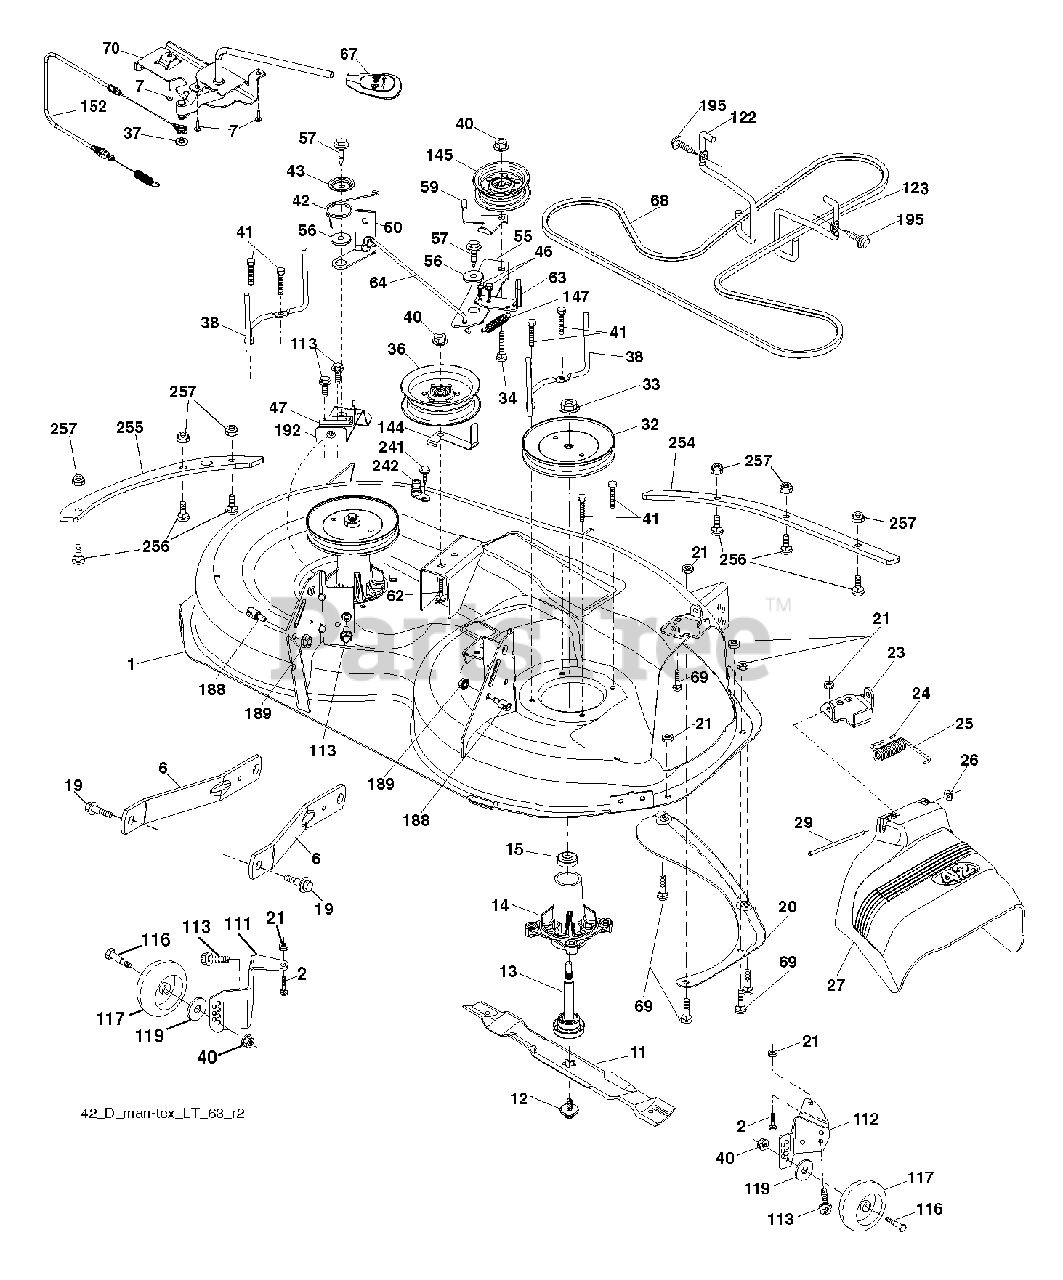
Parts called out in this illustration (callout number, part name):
1	DECK.SVC.42"2GW
2	BOLT 5/16C X 3/4" CARRIAGE
6	ARM.SUSPENSION.MOWER.R
7	SCREW.#10 X 0.750.BOS
11	42" HI-LIFT BLADE
12	SCREW.SEMS.7/16-20X1.HEX.HEAD
13	SHAFT ASM.MNDRL.N/GREASEABLE
14	HOUSING.MANDREL.4PT.
15	BEARING.MANDREL.TOP.EXTENDED
19	BOLT.SHOULDER
20	BAFFLE.VORTEX
21	LOCKNUT
23	BRKT.DEFLECTOR.38"2005+
24	CAP-SLEEVE LT
25	SPRING.TORSION.DEFLECT
26	NUT PUSH M
27	SHIELD.DEFLECTOR.MOWER.42"BLAC
29	ROD.HINGE
32	PULLEY.MANDREL.5.438.PD
33	NUT.FLANGE.LOCK.TOP
34	BOLT.3/8-16X1.50
36	PULLEY.IDLER.2006
37	WASHER
38	KEEPER.BELT.MANDREL.PULLEY
40	NUT LOCK FLG 3/8-16 UNC
41	BOLT.HEX.WASHR.HED.313-18X1.19
42	SPRING.TORSION.BRAKE
43	SRPING.TORSION.RETAINE
46	SCREW.1/4-20X5/8
47	BRKT.CLUTCH.CABLE
55	IDLER.ARM.42"
56	SPACER.RETAINER
57	SCREW 3/8-16X1
59	GUARD, BELT
60	ARM BRAKE MOWER
63	ARM BRAKE MOWER
64	LINKAGE.BRAKE.ASM.ZINC
67	HANDLE.CLUTCH.CABLE.LT
68	BELT.DECK.DRIVE.42"
69	BOLT
70	CLUTCH.ASM.MANUAL.YT.PREDATORQ
111	BRKT.WHEEL.GAUGE.LH.42"
112	BRKT.WHEEL.GAUGE.RH.42"
113	BOLT.5/16HEX.WHS.HD
116	BOLT M
117	Gage Wheel, Rally Narrow
119	WASHER
122	KEEPER BELT ENGINE LH
123	KEEPER BELT RH
144	KEEPER.BELT.MOWER
145	PULLEY.IDLER.48"PRIMARY
147	RETURN SPRING
152	CABLE.MECHANICAL.CLUTCH
188	STUD.FASTNER.W/ANTI-ROTATE
189	NUT LOCK HEX FLANGE 5/16-18
192	BRKT.BRAKE.STAND.LH.
195	SCREW, 3/8-16X3/4
241	SCREW.TT.#10-32X.5.3/8.FLANGE
242	PORT.WASHOUT
254	PLATES.RENFRC.42DECK.PT431FRNT
255	PLATES.RENFRCE.42DECK.X431SIDE
256	RHSNB, 1/4-20 X 1, GR5
257	NUT T
